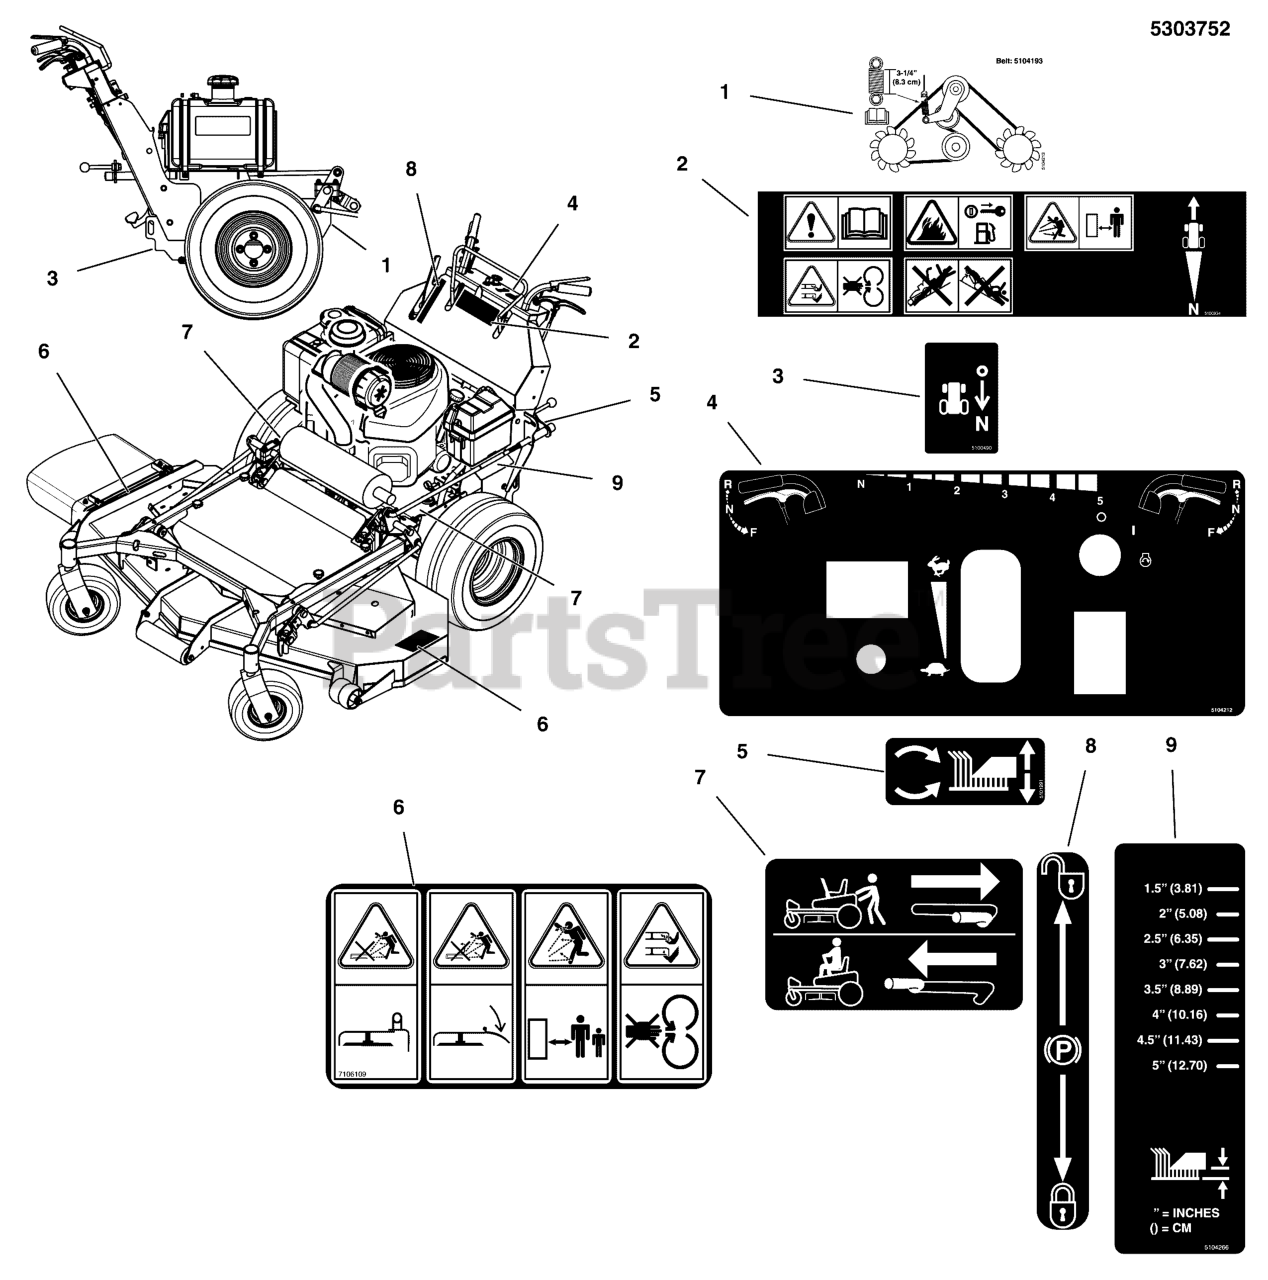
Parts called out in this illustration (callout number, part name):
1	DECAL, BELT ROUTING, F/SW35
2	DECAL, CCW, CE
3	DECAL, PEDAL
4	DECAL, DASH PANEL, WKB, MAN/ELEC START
5	DECAL, CUT HEIGHT, SPDD
6	DECAL, DISCHARGE SAFETY, EXPORT
7	DECAL, TRANSAXLE RELEASE, WB
8	DECAL, PARKING BRAKE SYMBOLS
9	DECAL, CUT HEIGHT, WB, 1.5"-5"
